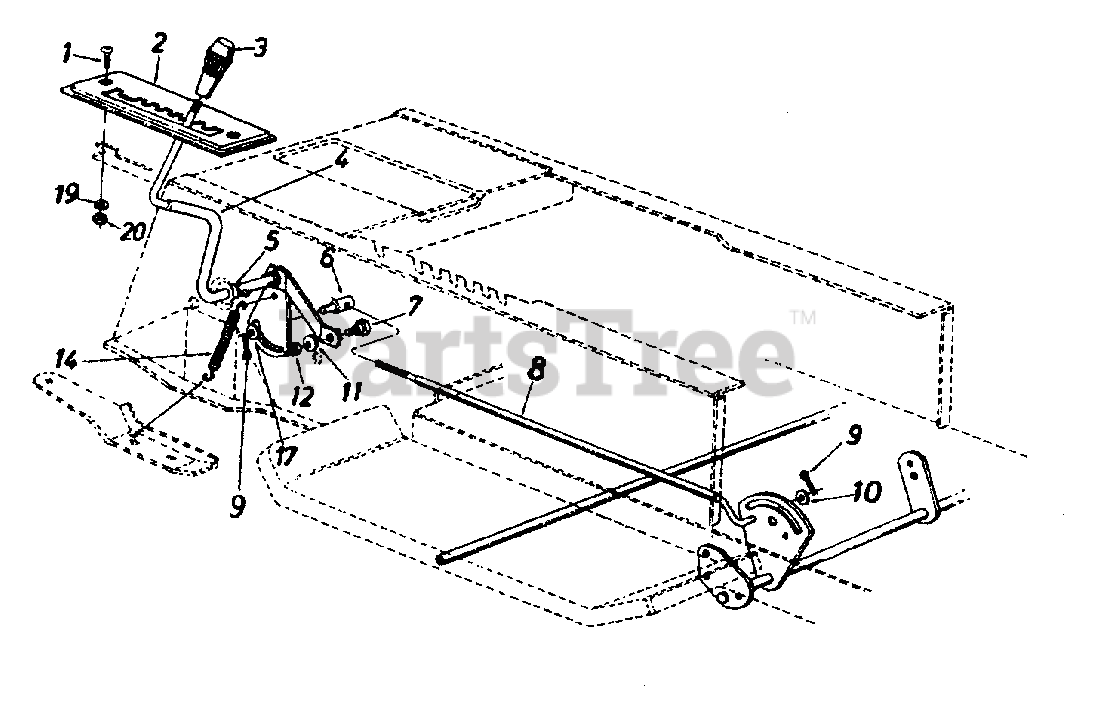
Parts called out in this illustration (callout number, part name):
1	Truss Mach. Scr. 1/4-20 x.75" Lg.
4	Speed Selector Lever Ass'y.
5	Flat Washer .53" I.D. x .93"
6	Ferrule 3/8-24 x .37" Dia.
7	Shoulder Bolt
8	Speed Control Link
9	Cotter Pin 3/32" Dia. x 1.0"
10	Fl-Wash. .469" I.D. x .88"
11	L-Wash. 5/16" I.D.
12	Hex Nut 5/16-18 Thd. (Gr. 5)
14	Spring .38" O.D. x 3.18" Lg.
17	Fl-Wash. .385" I.D. x 7/8"
19	L-Wash. 1/4" LID.
20	Hex Nut 1/4-20 Thd. (Gr. 5)
